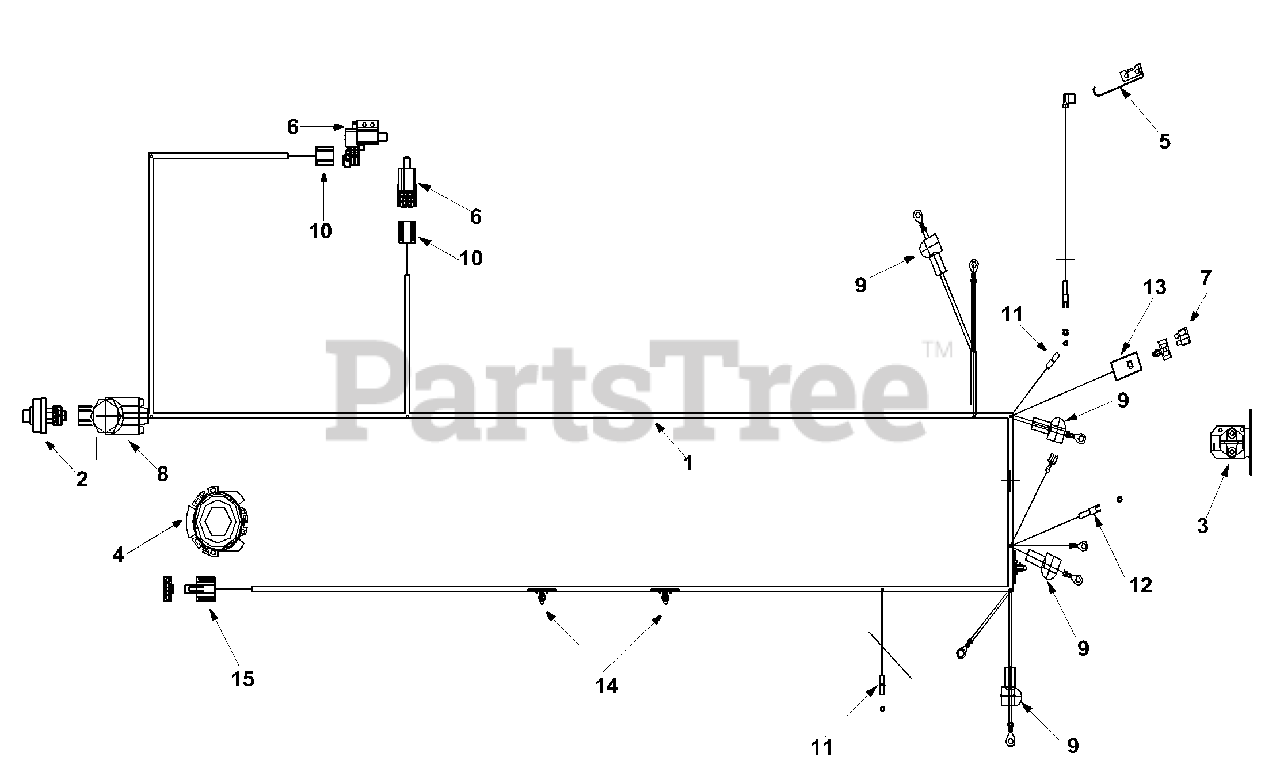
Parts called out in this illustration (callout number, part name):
1	Harness Assembly w/o relays
2	Ignition Switch: 5 Pin
3	Solenoid: 12 V. 100 amp.
5	Spring Switch
6	Interlock Switch
7	Fuse: 20 amp.
8	Battery Cover
9	Battery Cover: Red
13	Fuse Holder w/Clip
14	Harness Clip
